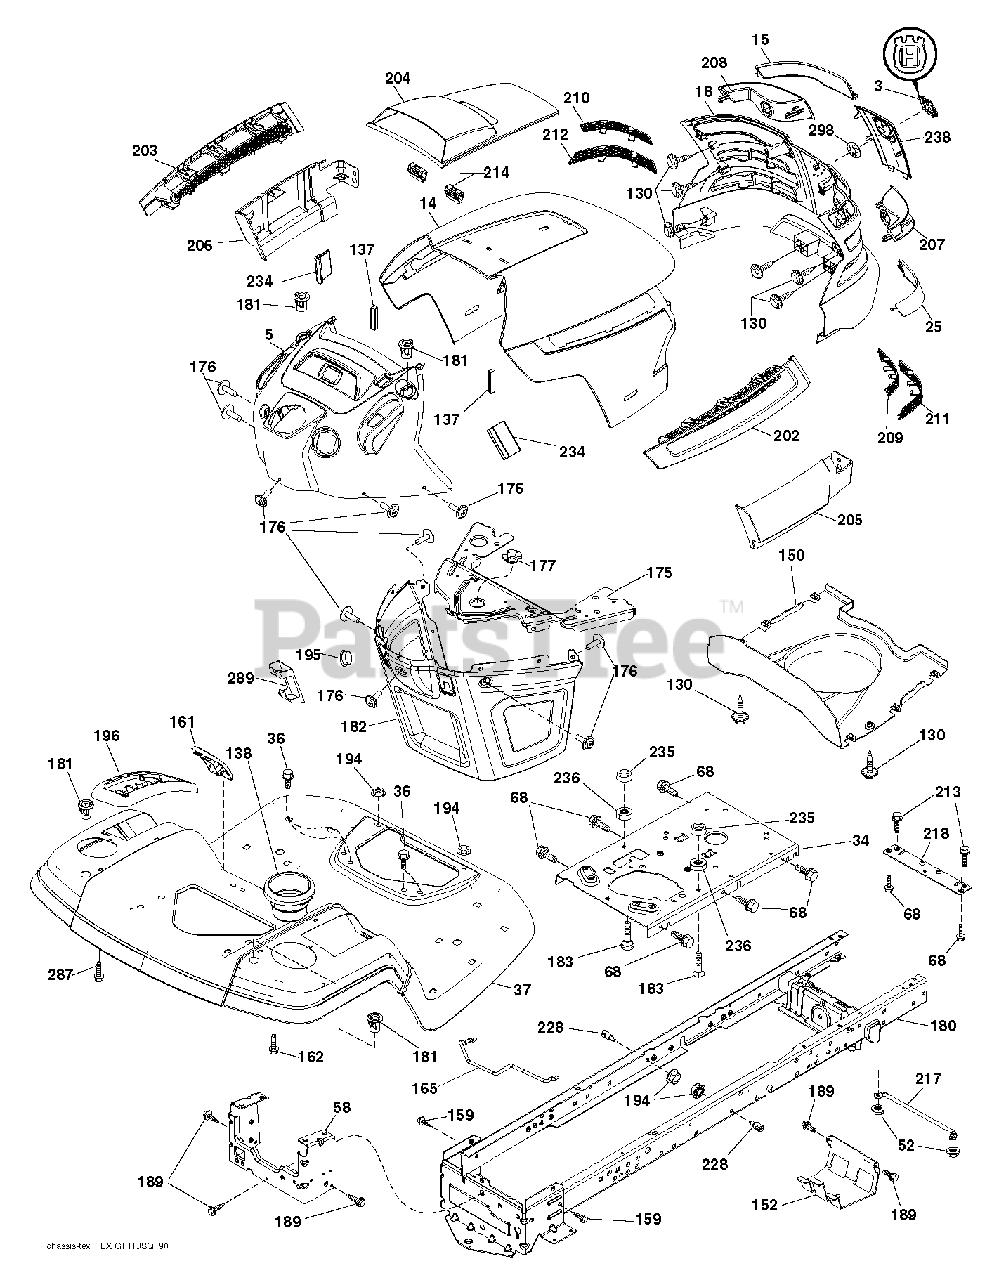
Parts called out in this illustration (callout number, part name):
3	RP LOGO
14	HOOD
15	LENS.LH.TEX.GT.HUSQ.CL
18	GRILL.ASM.HUSQ.TG/CRD.W/TRIM
25	LENS.RH.TEX.GT.HUSQ.CL
34	PLATE.ENGINE.WELDED.CHASSIS
36	SCREW 5/16"
37	FENDER.TLT.FS.W/CPH/FW/RSF.668
52	LOCKNUT
58	DRAWBAR UPPER 2PC SMALL FENDER
68	SCREW LT
130	SCREW.#10 X 0.750.BOS
137	BUMPER DASH
138	CUPHOLDER.TL.TEX.418
150	AIR.DUCT.TEXGT.HUSQ.31
152	SHIELD.BROWNING.W/TEX
159	SCREW, 3/8-16X3/4
161	RP WINDOW.FUEL.LT.TEX.GREY
162	SCREW.HI-LO.CONSOLE
165	SUPPORT.TANK.REAR.W/TEX
175	PLATE.CROSSMEMBER.HUSQ
176	SCREW.#10-24X5/8.RN.QU
177	BUSHING, STEERING
180	CHASS.WLDMNT.TL.12GA/2P.48/54
181	BUSHING.MNT.FEND.CRGO.
182	DASH.LOWER.COMMON.12V.ADAPTOR
183	BOLT.5/16-18X1-1/4 FULL THD
189	SCREW
194	NUT LOCK HEX FLANGE 5/16-18
195	PLUG.HOLE.DASH.LOWER.12V.BLK
196	RP CONSOLE.ASM.DECKLFT.GR/RBT.
202	VENT.SIDE.HOOD.RH.HUSQ
203	VENT,SIDE.HOOD.LH.HUSQ
204	HOOD VENT
205	HOOD SIDE SKIRT RH
206	SKIRT.HOOD.SIDE.HUSQ.L
207	BEZEL.RH.TEX.GT.HUSQ
208	BEZEL.LH.TEX.GT.HUSQ
209	INSERT.HEX.GRILL.HUSQ.GREY
210	INSERT.HEX.GRILL.HUSQ.
211	INSERT.HEX.GRILL.HUSQ.
212	INSERT.HEX.GRILL.HUSQ.
213	BOLT
214	CLIP.RETAINER.TINNER.
217	ROD.PIVOT.HOOD
218	X-PIECE.HOOD.STOP.NON/
228	STUD.FASTNER.W/ANTI-ROTATE
234	BUMPER.HOOD.TEX.HUSQVARNA
235	SPACER FENDER
236	NUT.CENTERLOCK.5/16-
238	TRIM.HUSQ.TG/CRD.SERVICE
287	SCREW 1/4X20
289	PLUG.N/CRUISE.COMMON.YT/GT.BLK
298	NUT PUSH M
